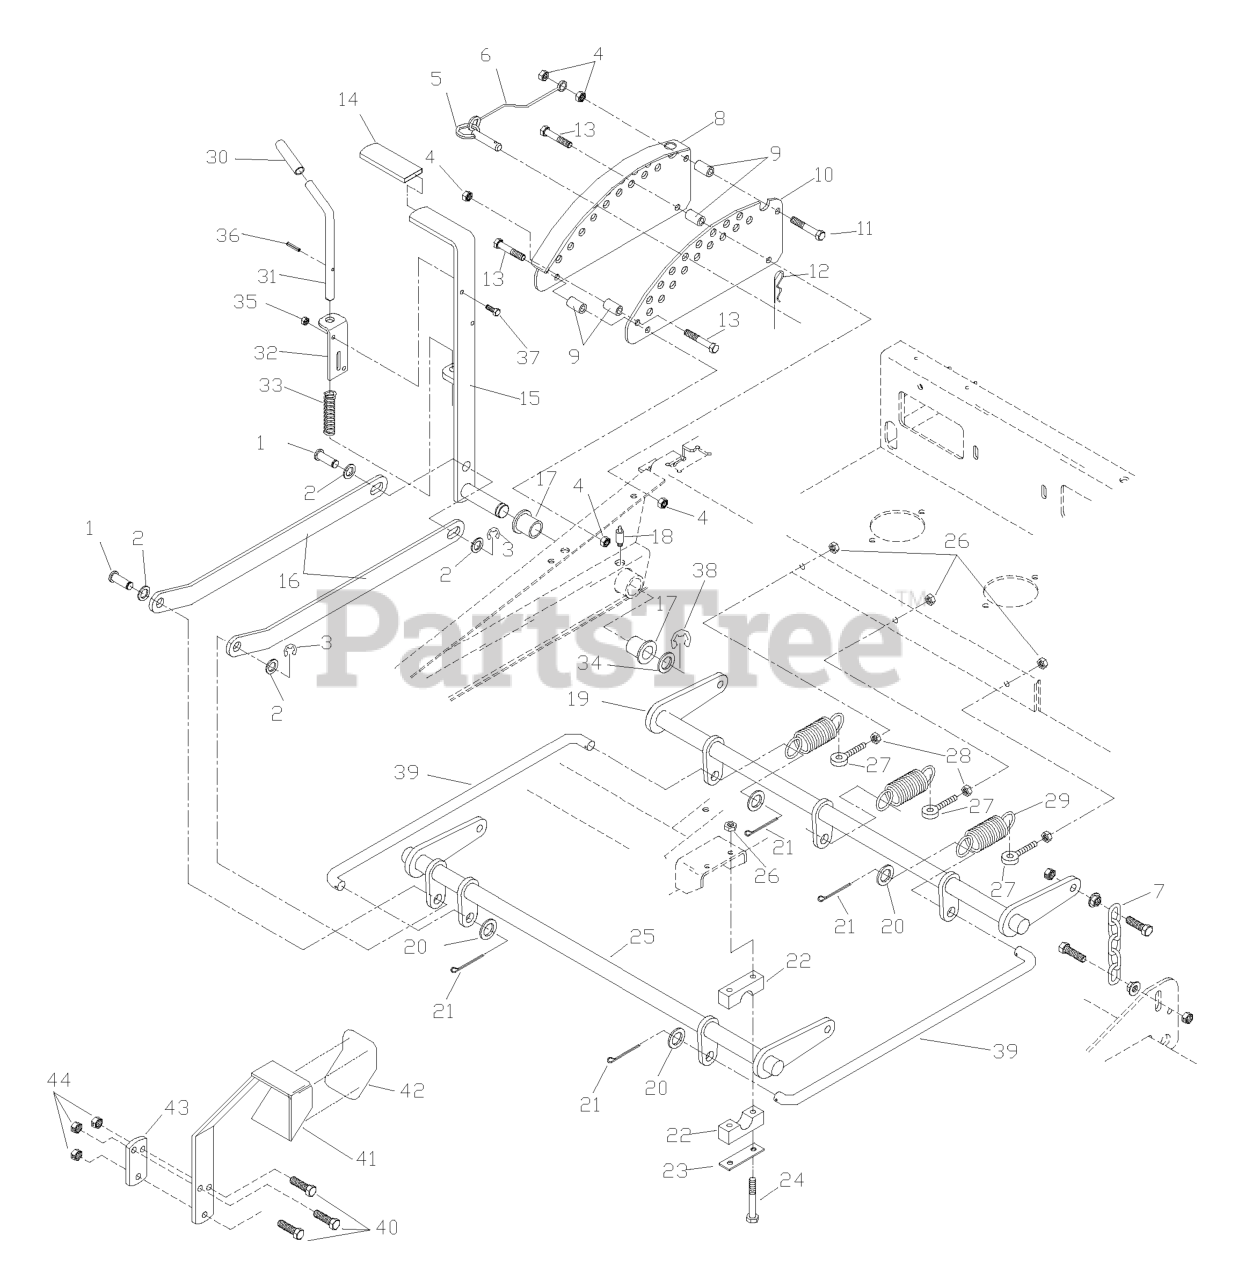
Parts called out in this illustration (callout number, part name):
1	CLEVIS PIN
3	E-RING 5/8
4	NUT 3/8C CENTERBLOCK
7	LIFT CHAIN
8	ADJ. PLATE WLDMNT
9	DECK LIFT SPACER
10	ADJ. PLATE PAINTED
11	HCS 3/8C X 2 1/2
12	HAIRPIN #4
13	HCS 3/8C X 2 1/4
15	LIFT LEVER WELDMENT
16	LIFT LINKAGE,PAINTED
17	BUSHING, FLANGED
18	GREASE ZERK LONG
19	SHAFT LIFT REAR
20	WASHER 5/8 FLAT
21	COTTER PIN
22	PILLOW BLOCK
23	REINFORCEMENT BAR
24	BOLT 5/16C X 2 1/2
25	LIFT SHAFT
26	NUT 5/16C CENTERLOCK
27	EYEBOLT, RH
28	NUT 5/16C WHIZ
29	DECK LIFT SPRING
32	PIN MT, UPPER
34	BSHG .875 X 1.375 X .074 ZD
35	NUT 1/4C CENTER LOCK
36	ROLL PIN 3/16 X 1-1/4 ZD
37	HCS 1/4C X 3/4 HCS
38	E-RING 7/8
39	CONNECTING LINK
40	HCS 3/8C X 1 1/2
41	LIFT PEDAL BLK
42	ANTI-SKID PAD
43	TIGHTENING PLATE BLK
44	NUT 3/8-16 NYLOC
